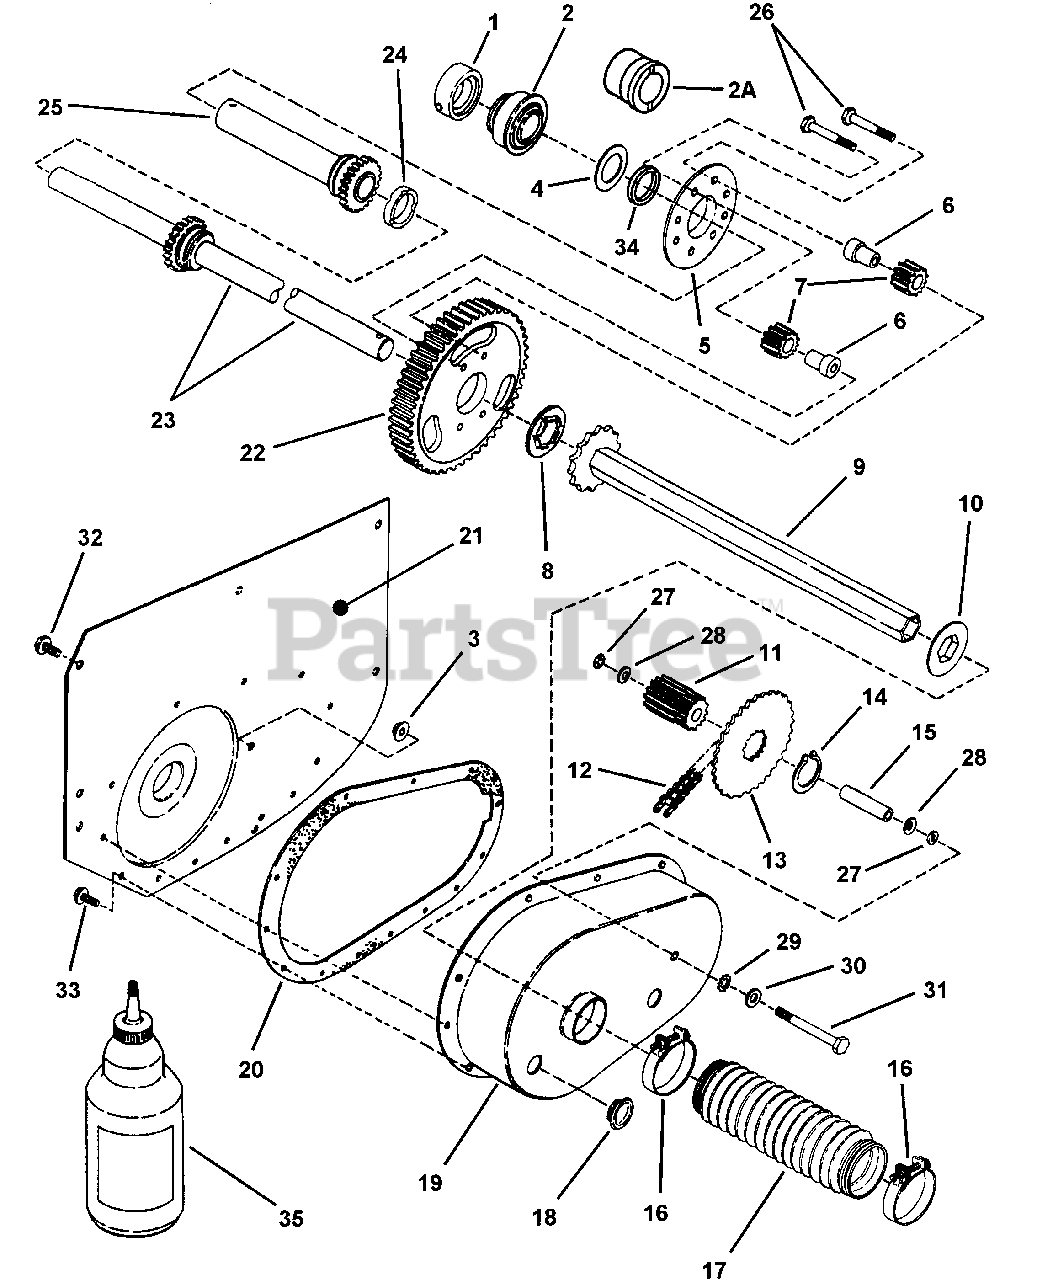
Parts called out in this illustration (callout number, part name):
1	COLLAR, Lock
2	BALL BEARING, Axle (Right Hand Fender)
2A	BEARING, Axle (Right Hand Fender)
3	NUT, 5/16-24 Hex Flange Lock
4	WASHER, Thrust
5	PLATE, Differential
6	SPACER, Pinion
7	GEARS, Differential Pinion
8	WASHER, Thrust
9	ASSEMBLY, Drive Hex Tube
10	WASHER, Hex Nylon Splash
11	GEAR, 11 Teeth-10 Pitch
12	CHAIN, 46 Pitch (No. 35)
13	SPROCKET
14	RING, External Retaining
15	SPACER
16	CLAMP, Boot
17	BOOT, Oil Seal
18	PLUG, Oil Fill & Check
19	CASE, Transmission
20	GASKET, Transmission Case
21	FENDER, Right Hand
22	GEAR, 63 Teeth-10 Pitch
23	AXLE, Long
24	SPACER, Differential (1.25" ID x .425 Wide)
25	AXLE, Short
26	SCREW, 5/16-24 x 1-5/8" Hex Cap Special Lock
27	O-RING, 5/16"
28	WASHER, 5/16" Belleville
29	WASHER, 5/16" External Tooth Lock
30	WASHER, 5/16" Flat
31	BOLT, 5/16-24 x 2-5/8" Idler
32	SCREW, 5/16-18 x 5/8" Hex Washer Self-Tap
33	SCREW, 1/4-20 x 5/8" Hex Washer Self-Tap
34	SPACER, Short Axle
35	GREASE, Transmission (24 oz. Required)
